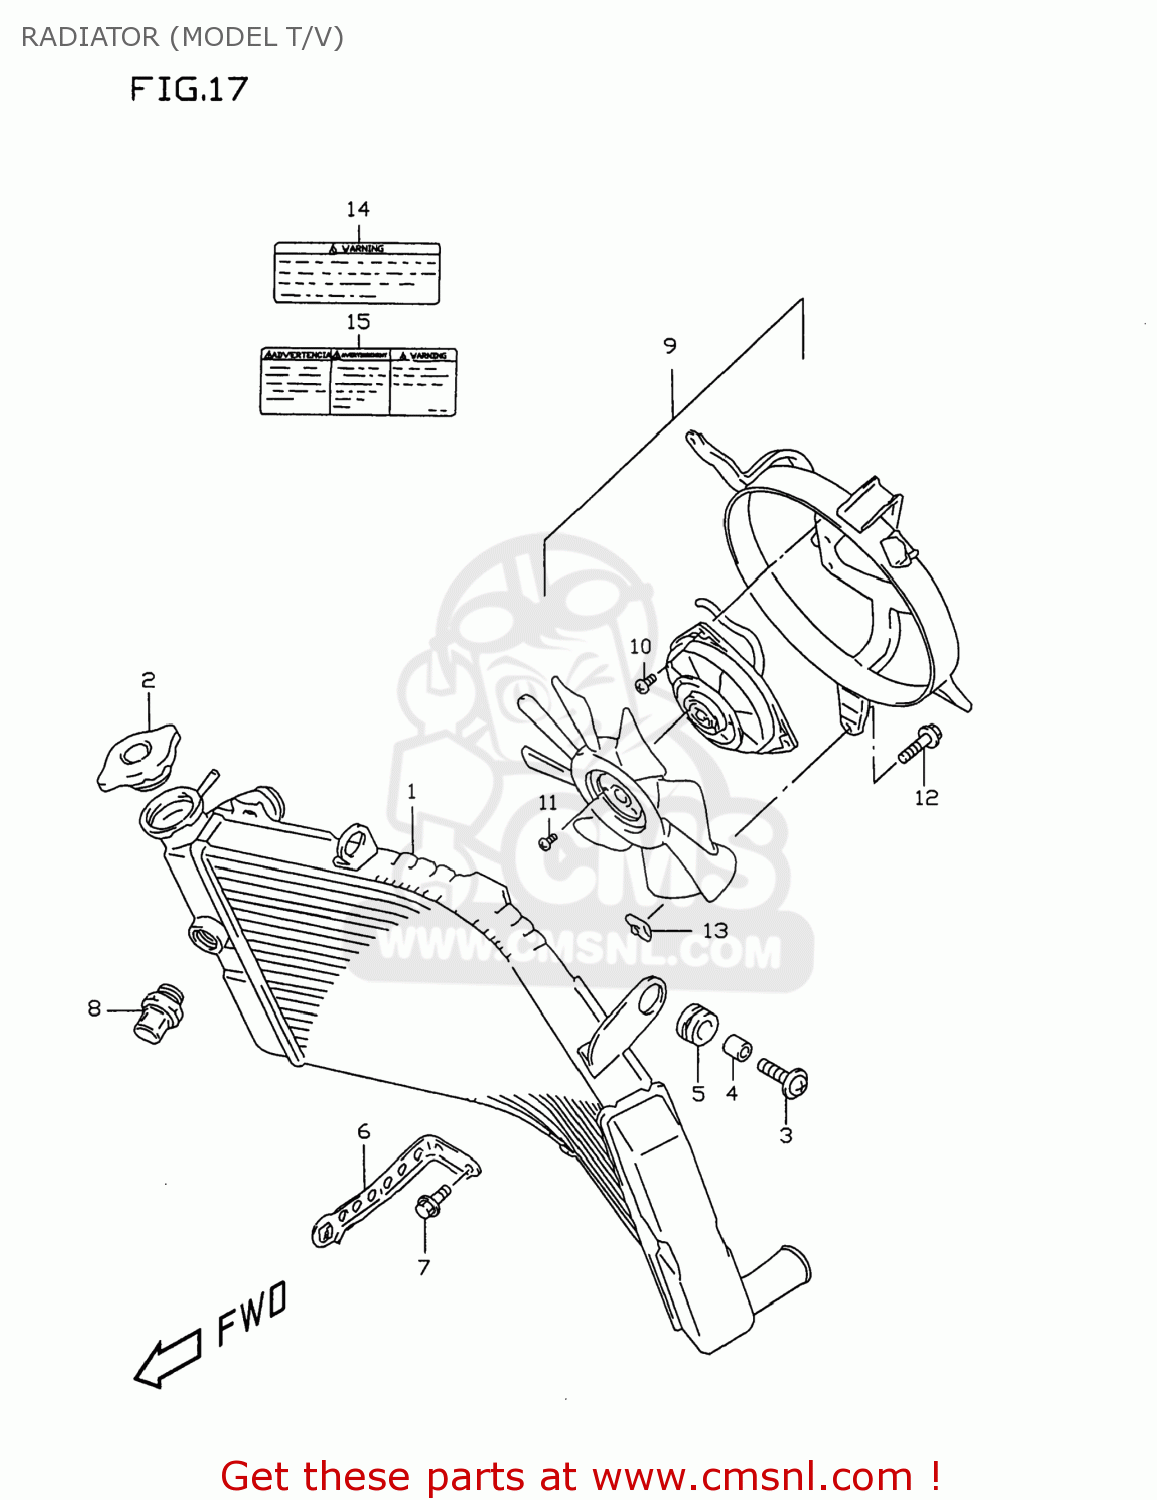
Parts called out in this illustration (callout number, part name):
1	RADIATOR ASSY,WATER
2	CAP,RADIATOR
3	BOLT 6X20
4	SPACER(6.5X10X12)
5	CUSHION
6	BRACKET,RADIATOR LWR
7	BOLT
8	SWITCH,RADIATOR FAN
9	FAN ASSEMBLY,RADIATOR
10	SCREW
11	SCREW 4X6
12	BOLT
13	NUT,RADIATOR COVER
14	LABEL,ENGINE COOLING FAN
15	LABEL, COOLING FAN
